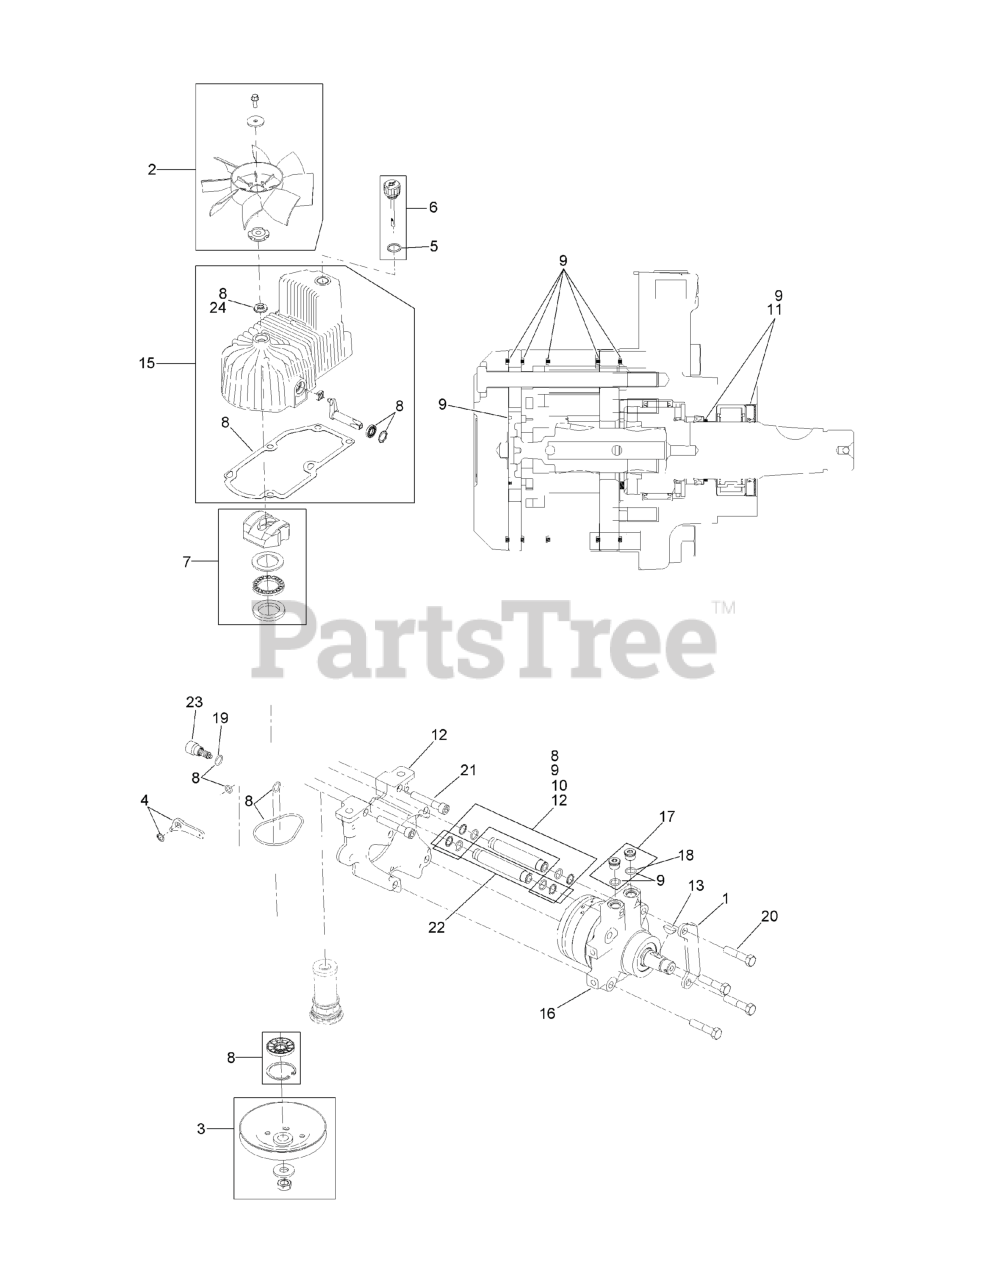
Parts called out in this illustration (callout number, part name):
1	MOUNT-SHOE, HORSE
2	FAN KIT
3	PULLEY KIT
4	HANDLE-BYPASS VALVE, HYDRO
5	GASKET-DIPSTICK, HYDRO
6	DIPSTICK-HYDRO W/GASKET
7	SWASH BLOCK KIT
8	PUMP SEAL KIT
9	MOTOR SEAL KIT
10	TUBE SEAL KIT
11	OUTPUT SHAFT SEAL KIT
12	NOSE CUP-UHT
13	KEY-WOODRUFF
15	HOUSING-HYDRO, RH
16	MOTOR-HYDRAULIC, RH 280CC
17	MAGNETIC PLUGS SERVICE KIT
19	O-RING-CHECK VALVE
20	SCREW HH
21	SCREW-HSH
22	HYDRAULIC TUBE KIT
23	SHOCK VALVE, 16CC HYDRO
24	SEAL-FAN DRIVE
25	Kit, Pump Section 16Cc RH
26	Kit, Rotating Grp 16Cc RH
99	PULLER-PULLEY
